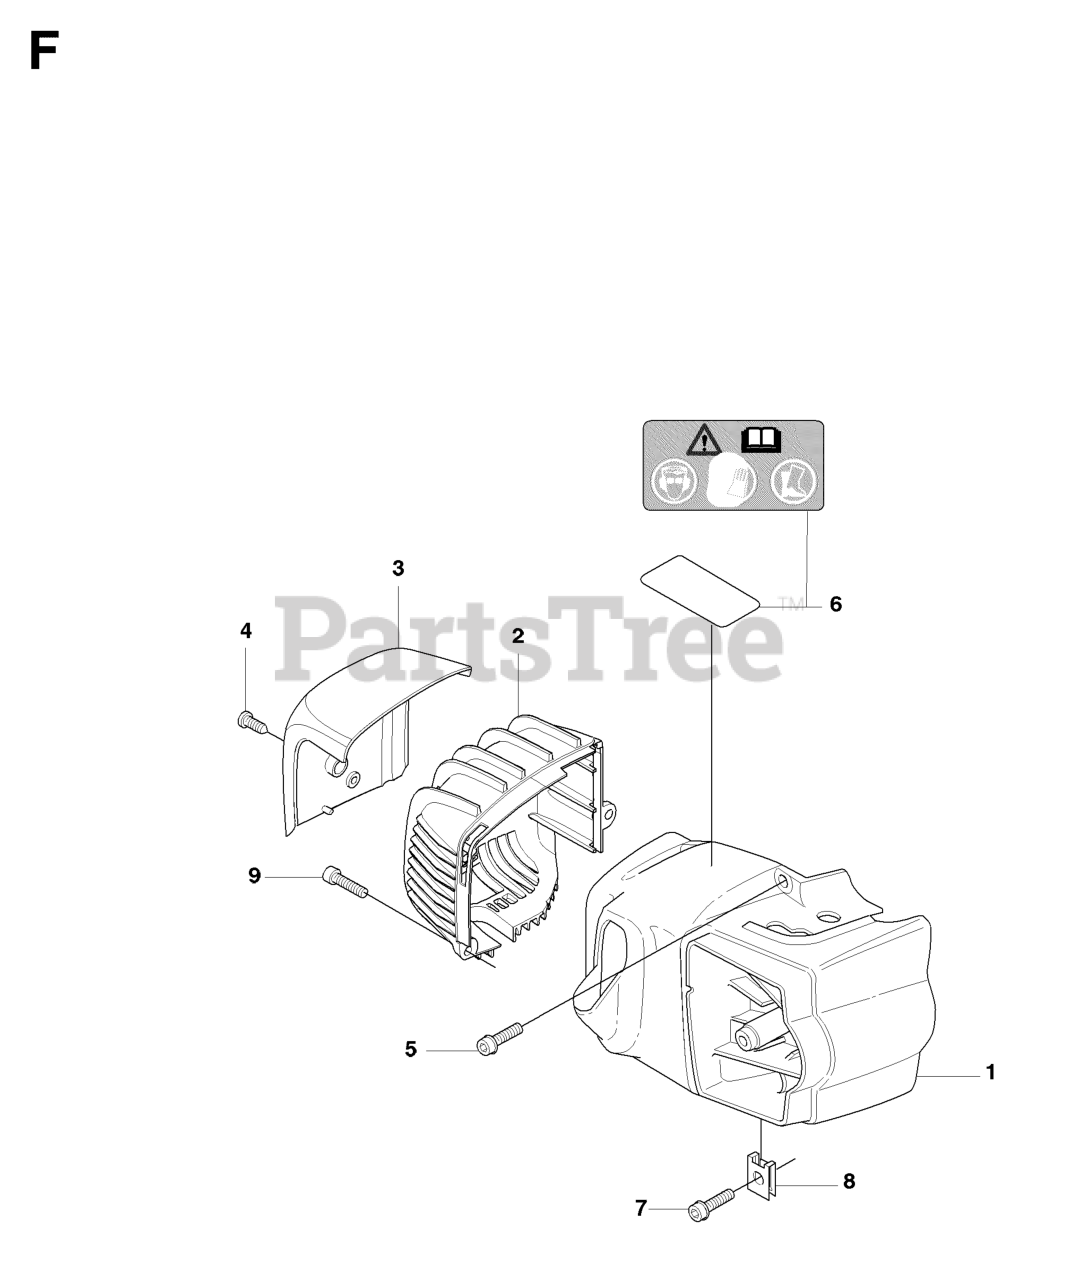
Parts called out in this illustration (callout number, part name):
1	CYLINDER COVER
2	RP MUFFLER COVER
3	MUFFLER SHIELD
9	SCREW W/ LOCKING FLUID
